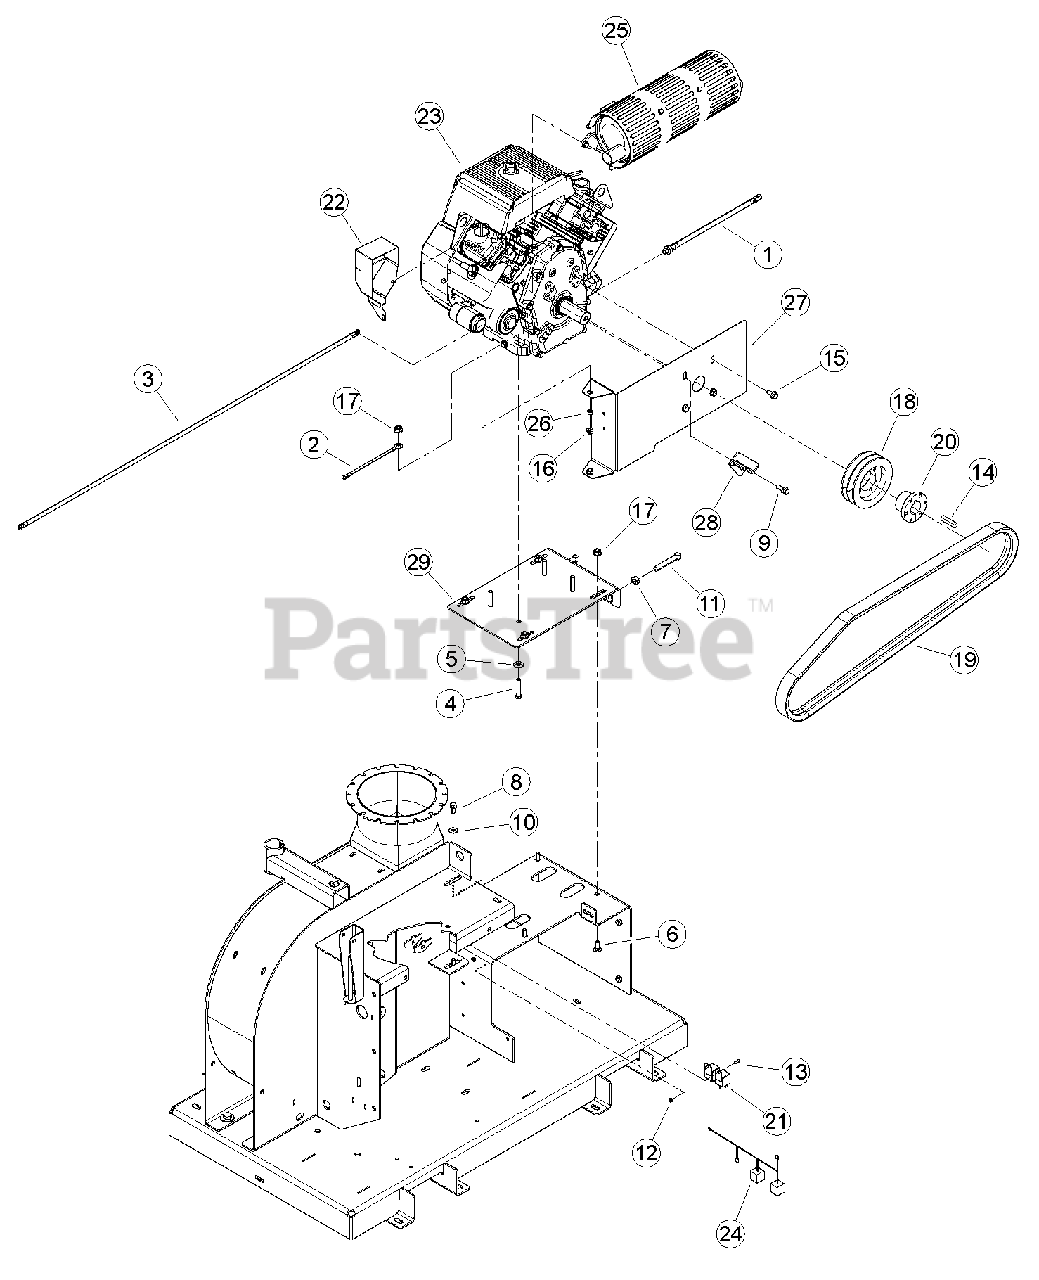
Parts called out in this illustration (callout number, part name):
1	HOSE ASSEMBLY, CRANKCASE DRAIN
2	CABLE, 50" NEG (R/R)
3	CABLE, 48" POS (R/R)
4	BOLT, 3/8 X 2 GR5 HEX CAPSCREW ZP
5	WASHER, 3/8" FLAT ZP
6	BOLT, 3/8 X 1" GR5 CRG NC ZP
7	NUT, 1/2 NC ZP JAM
8	BOLT, 5/16 X 3/4 FLANGE NC
9	BOLT, 3/8 X 1 FLANGE NC
10	WASHER, 5/16" FLAT ZP
11	SETSCREW, 1/2 X 3 SQ HD 1/2 DOG PT
12	NUT, 10/24 NYLOCK TYPE NM ZP
13	SCREW, MCH 10-24 X 1/2" PAN HD PH ZP
14	KEY, 3/8" SQ X 2" LG PLAIN
15	BOLT, 3/8 X 3/4" SERRATED FLANGE
16	NUT, 5/16-18 NYLOCK-FLANGE
17	NUT, 3/8-16 NYLOCK FLANGE
18	SHEAVE, 2B5.2 SDS
19	BELT, 2B70 BANDED ARAMID
20	BUSHING, SD 1-7/16"
21	RELAY, 12V SPDT W/ FLANGE
22	CONTROL, SUBARU V-TWIN IGNITION (FOR SERVICE SEE ENGINE OWNER'S MANUAL OR YOUR NEAREST SUBARU INDUSTRIAL ENGINE DEALER)
23	ENGINE, SUBARU 720CC EH72 (FOR SERVICE SEE ENGINE OWNER'S MANUAL OR YOUR NEAREST SUBARU INDUSTRIAL ENGINE DEALER)
24	HARNESS, CARB SAFETY RELAY
25	MUFFLER, SUBARU OIL FILTER SIDE (FOR SERVICE SEE ENGINE OWNER'S MANUAL OR YOUR NEAREST SUBARU INDUSTRIAL ENGINE DEALER)
26	SPACER, .334 X .50 X .29
27	PLATE, DL ENGINE SHIELD
28	GUIDE, BELT DL ENGINE MOUNT
29	WELDMENT, ENGINE PLATE
